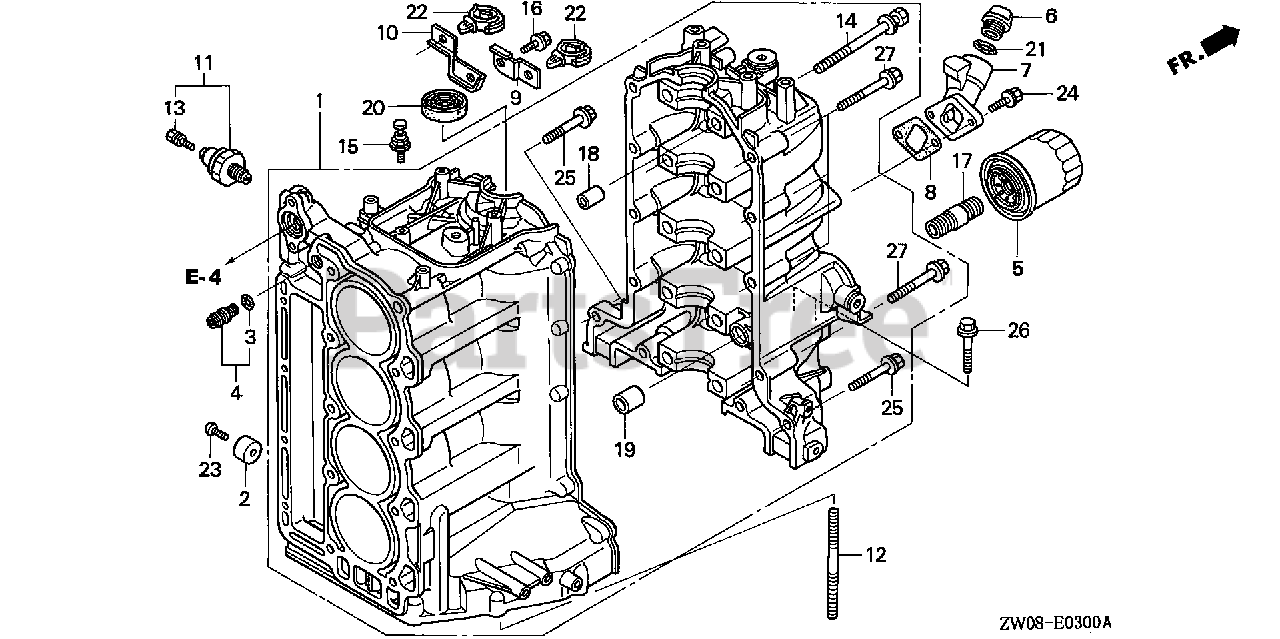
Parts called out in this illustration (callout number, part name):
1	BLOCK ASSY., CYLINDER *NH8* (DARK GRAY)
2	METAL, ANODE
3	O-RING (10.8X2.4) (ARAI)
4	ORIFICE ASSY., OIL PASSAGE
5	FILTER, OIL (FILTECH TOYO ROKI) (SOLD INDIVIDUALLY)
5	FILTER, OIL (Honda Code 6836290). (SOLD INDIVIDUALLY)
6	CAP, OIL
7	EXTENSION, OIL FILLER
8	GASKET, EXTENSION OIL FILLER (NON-ASBESTOS)
9	BRACKET, HARNESS CLIP
10	CLAMP C, ENGINE WIRE HARNESS
11	SWITCH, OIL PRESSURE
12	BOLT, STUD (10X125)
13	SCREW-WASHER (4X8)
14	BOLT-WASHER (10X112)
15	BOLT, TIMING BELT ADJUSTING SPRING
16	BOLT, FLANGE (6X14) (CT200)
17	HOLDER, OIL FILTER
18	PIN, DOWEL (12X18)
19	PIN, DOWEL (18X22)
20	OIL SEAL (38X50X8)
21	O-RING (26X2.7)
22	CLIP, WIRE HARNESS *NH1L* (BLACK)
23	SCREW, PAN (6X18)
24	BOLT, FLANGE (6X22)
25	BOLT, FLANGE (8X35)
26	BOLT, FLANGE (8X40)
27	BOLT, FLANGE (8X50)
